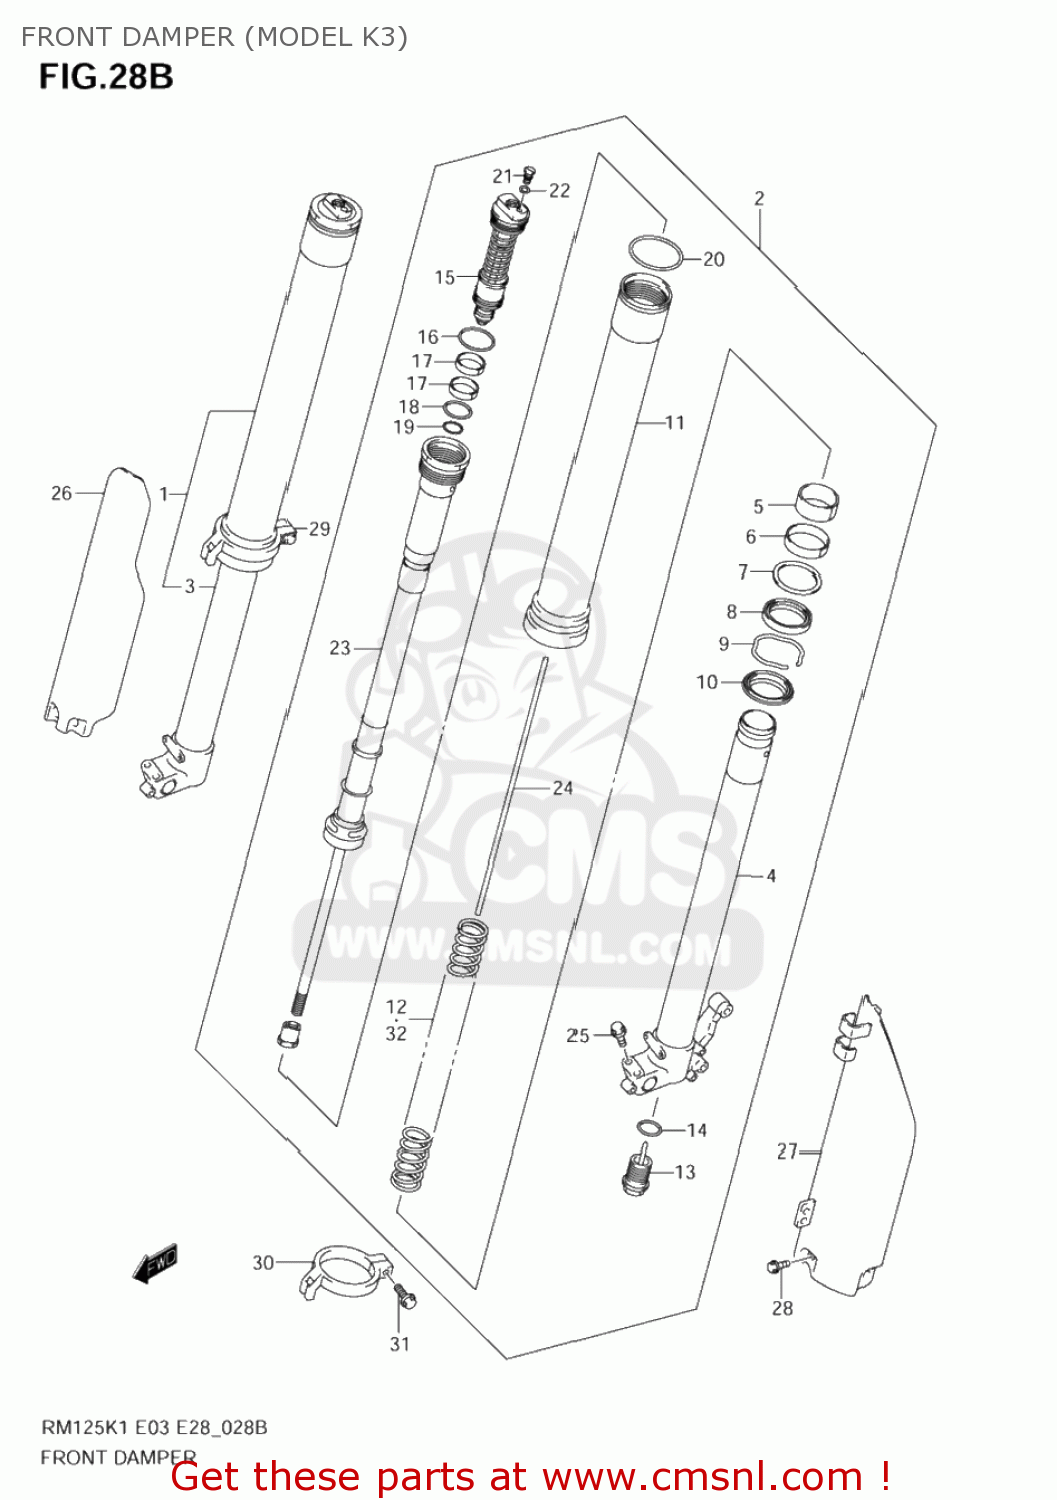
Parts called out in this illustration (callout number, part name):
1	DAMPER ASSY,FR FORK,R
2	DAMPER ASSY,FR FORK,L
3	TUBE,INNER,R
4	TUBE,INNER,L
5	BUSH,SLIDE
6	BUSH,GUIDE
7	SPACER,SEAL
8	SEAL,OIL
9	RING,OIL SEAL
10	SEAL,DUST
11	TUBE,OUTER
12	SPRING,FR(K=0.42)
13	BOLT,CTR
14	O RING
15	BOLT,FORK
16	O RING
17	BUSH,FORK BOLT SLIDE
18	O RING
19	O RING
20	O RING
21	BOLT,PLUG
22	O RING,PLUG
23	ROD,DAMPER
24	ROD,PUSH
25	BOLT
26	PROTECTOR FORK,R
27	PROTECTOR,FORK,L
28	BOLT(6X10)
29	GUIDE,PROTECTOR,R
30	GUIDE,PROTECTOR,L
31	BOLT
32	SPRING,FR(K=0.44)
